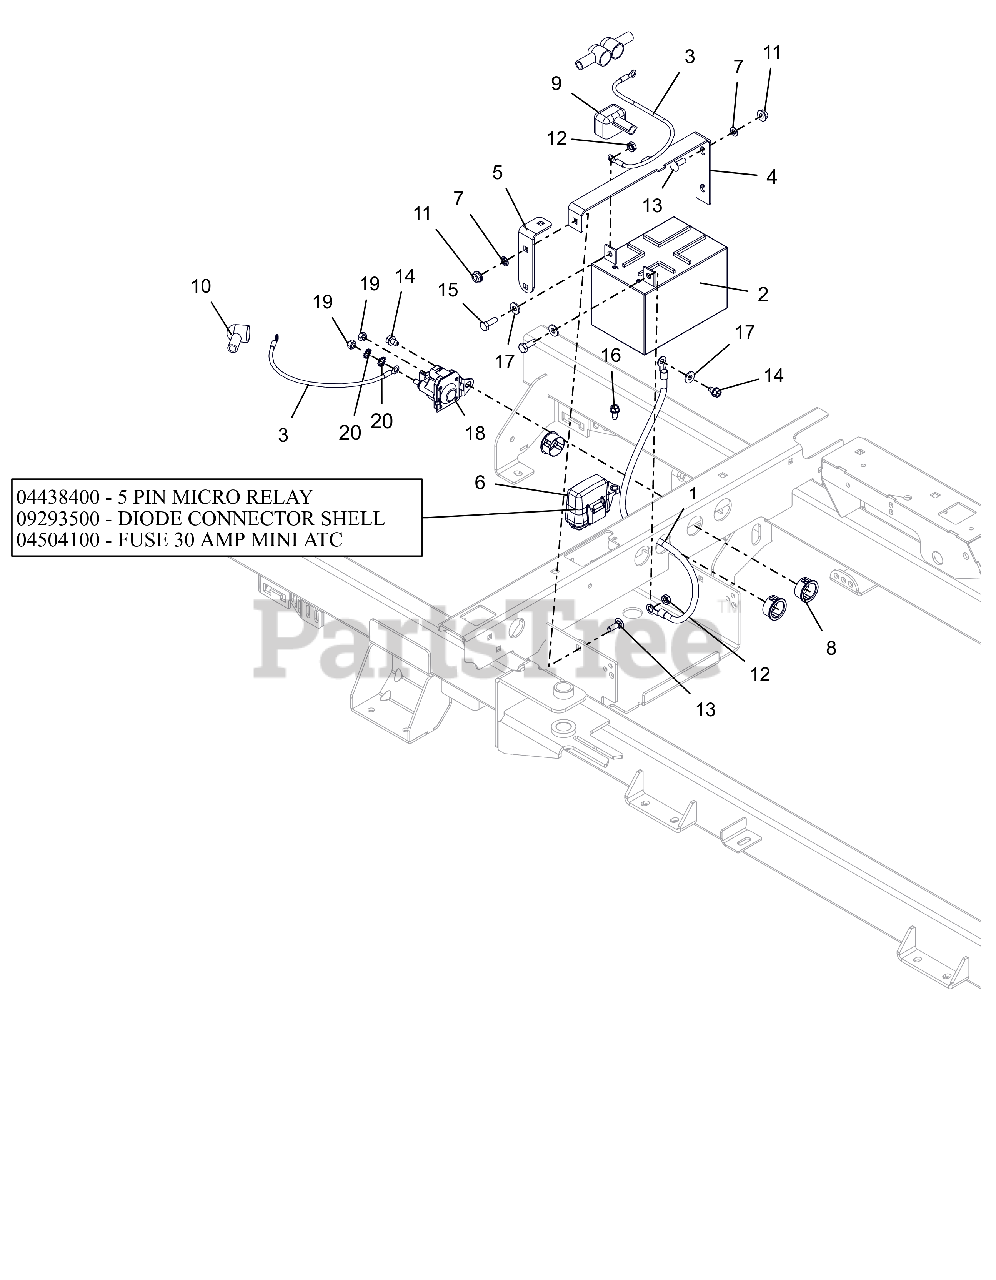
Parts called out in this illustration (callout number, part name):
1	CABLE-NEGATIVE BATTERY 24.00"
2	BATTERY, 12V 12A-190CCA
3	CABLE,POS W/2 1/4 RING 15.0 LG
4	BRKT, BATTERY HOLD-DOWN
5	BRKT, BATTERY HOLD DOWN
6	HARNESS, WIRE-4POS KEY IKON/ZT
6	RELAY,MICRO5 TERML W/RESISTOR
6	DIODE, CONNECTOR SHELL
6	FUSE,30 AMP MINI-ATC
7	NUT-PUSH .25X.50 O.D.
8	BSHG, PANEL SNAP .937X1.11X.56
9	INSULATOR
10	BOOT, EYELET TERMINAL
11	NUT-LK-TOP-FLG .250-20 GF ZCC
12	NUT-KEPS .250-20
13	BLT, RHSN .25-20X.750 G5 ZCC
14	SCR,TAP .25-20X.375 HWH TR ZCC
15	BLT, HEX .25-20X.75 G5 ZCC
16	SCR-TAP .25-20X.50 HWH ZCC
17	WSHR,FLT .281X.625X.065 ZCC
18	SOLENOID, STARTER (SEALED)
19	NUT-STD M6-1.0 ZCC
20	WSHR,LK-EXT.262X.502X.026 ZCC
